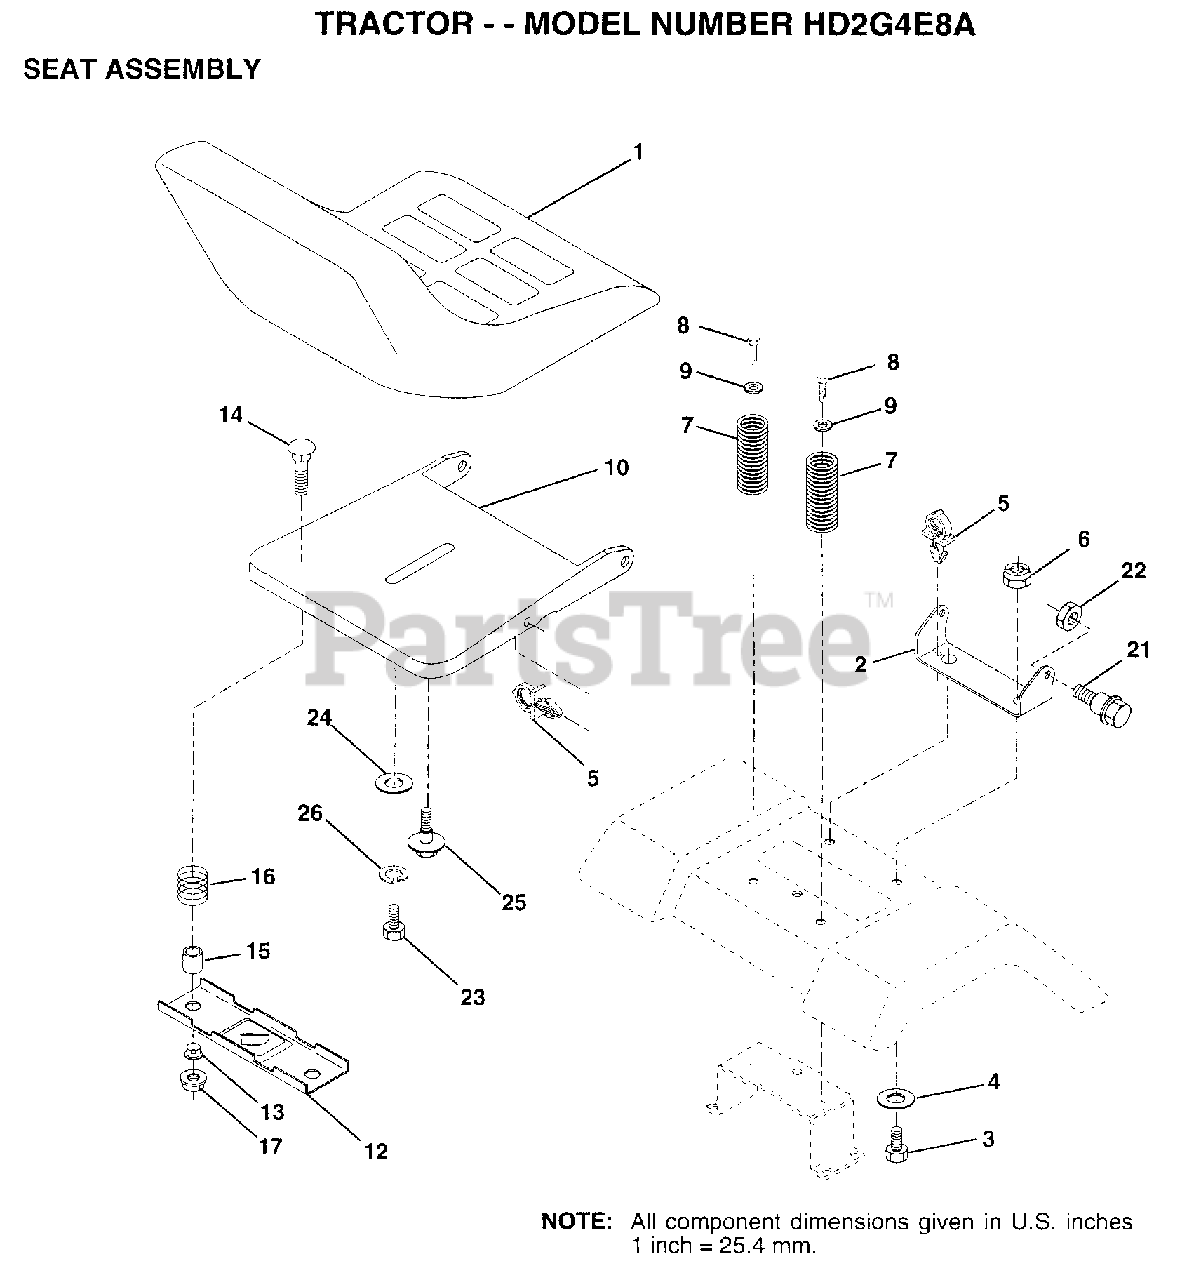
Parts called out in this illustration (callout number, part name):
1	SEAT
2	BRACKET PVT SEAT
3	BOLT
4	WASHER PM
5	CLIP.PUSH-IN.HING
6	NUT
7	SPRING COMPRESSIO
8	SCREW GTV
9	WASHER
12	BRKT SWITCH
13	BUSHING
15	SPLIT SPACER
16	SPRING
21	BOLT.SHLD.5/16-18
22	NUT
23	BOLT
24	WASHER
25	"BOLT,SHOULDER"
26	LOCKWASHER
